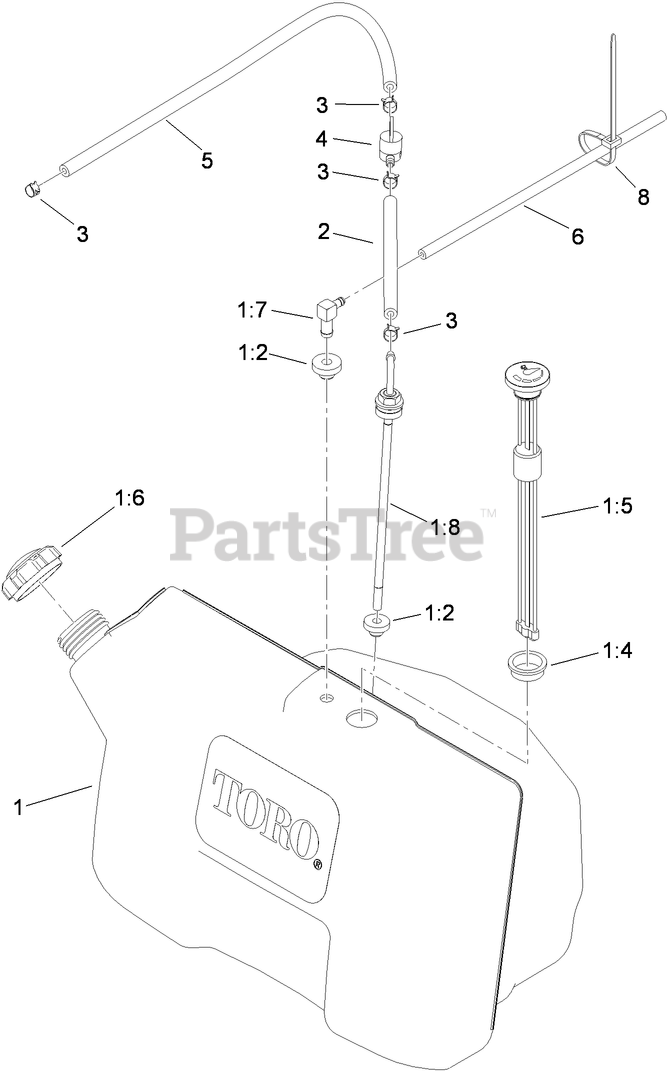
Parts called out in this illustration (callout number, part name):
1	TANK ASM
1:2	BUSHING
1:4	GROMMET
1:5	GUAGE-FUEL
1:6	CAP-FUEL
1:7	ELBOW-90 DEG
1:8	FITTING-FUEL, BULKHEAD
2	HOSE-FUEL
3	CLAMP-HOSE
4	VALVE-FUEL
5	HOSE-FUEL
6	HOSE-FUEL
8	TIE-CABLE
